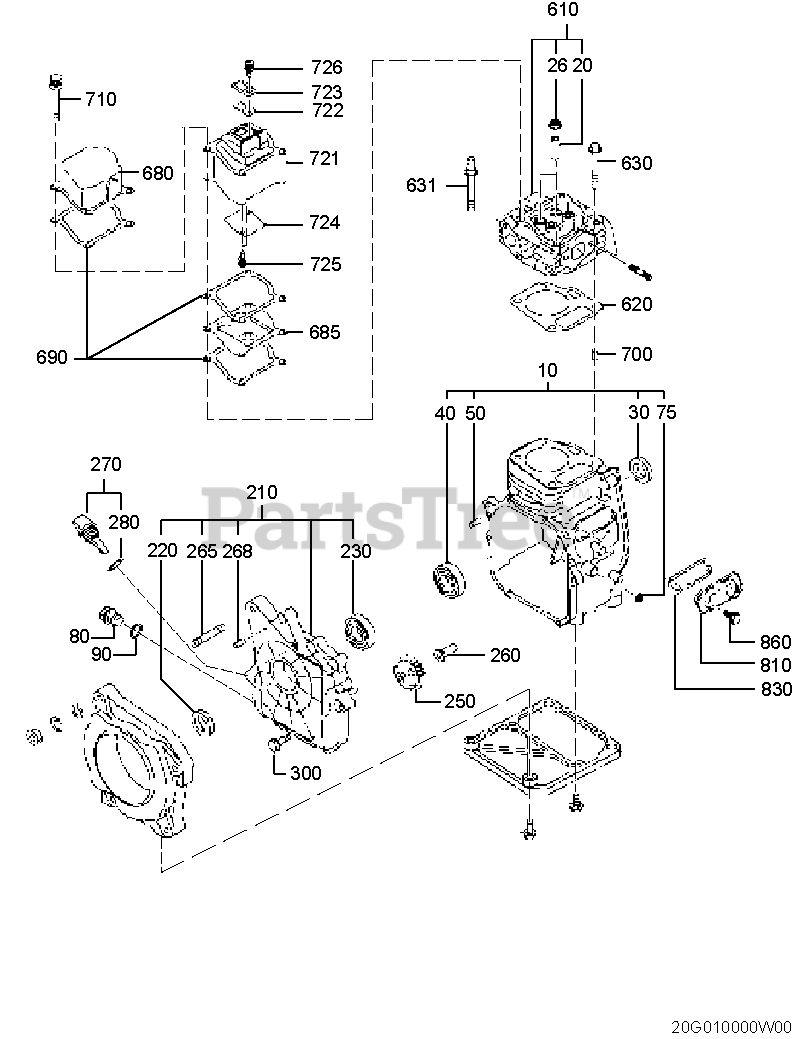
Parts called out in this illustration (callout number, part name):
210	MAINBEARING COVER CP
250	GOVERNOR GEAR CP
260	GOVERNOR SLEEVE
300	BOLT AND WASHER AY
610	CYLINDER HEAD AY
631	BOLT
685	OIL SHELTER PLATE 2
690	GASKET (ROCKER COVER)
721	BREATHER PLATE
723	RETAINER PLATE
724	OIL SHELTER PLATE 1
725	SCREW AND WASHER AY
726	SCREW AND WASHER AY
830	GASKET(TAPPET COVER)
860	BOLT AND WASHER AY
